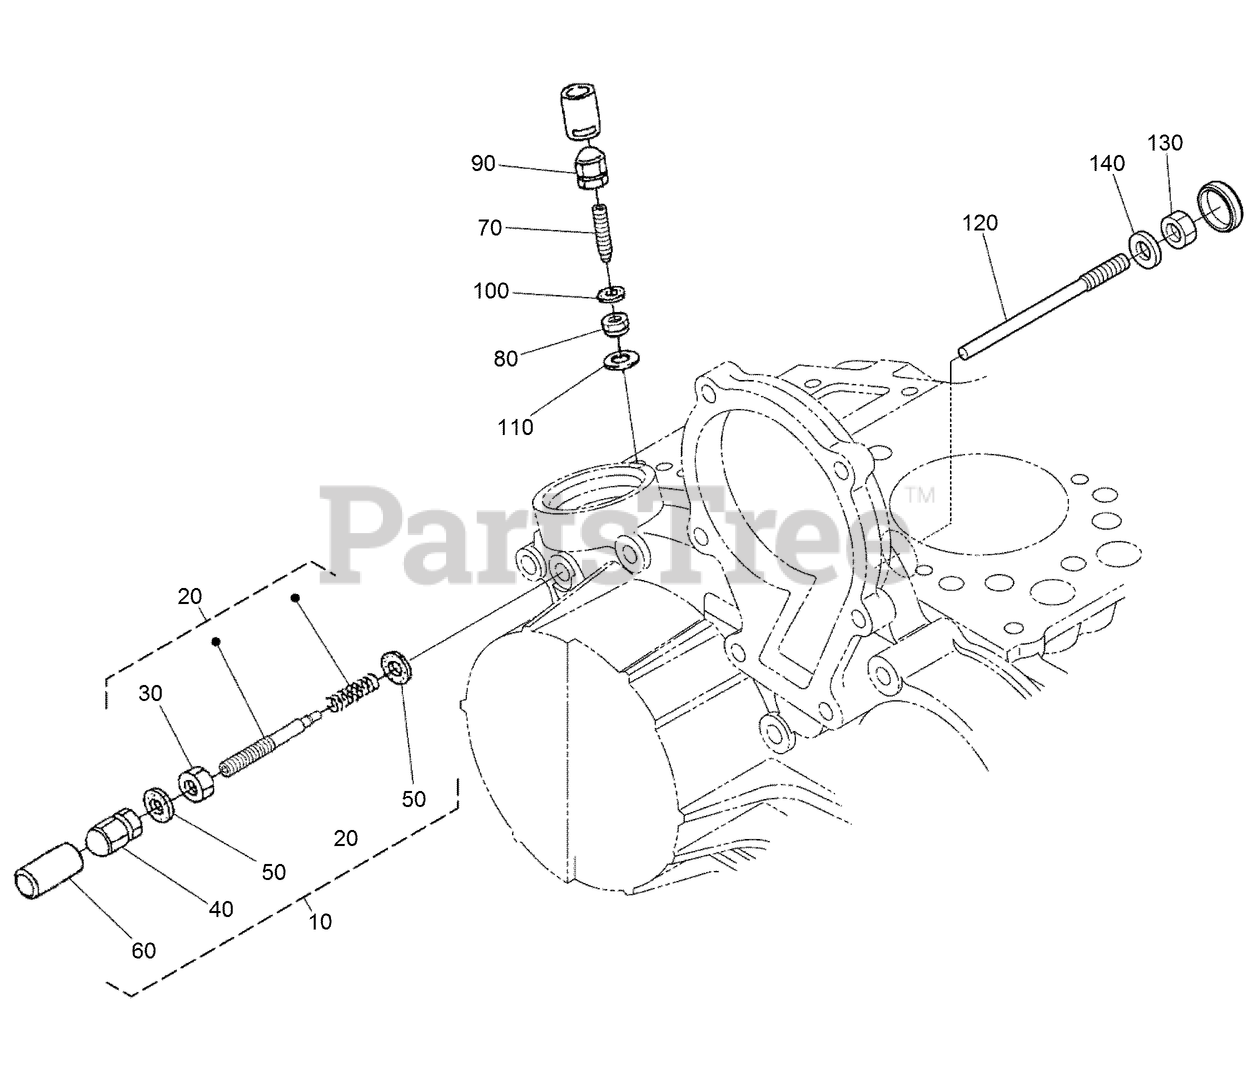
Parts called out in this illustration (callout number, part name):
10	APPARATUS-IDLING
20	ADJUSTMENT BOLT ASM
50	GASKET
70	BOLT-ADJUSTING
80	NUT-LOCK
100	GASKET
110	GASKET
140	GASKET
